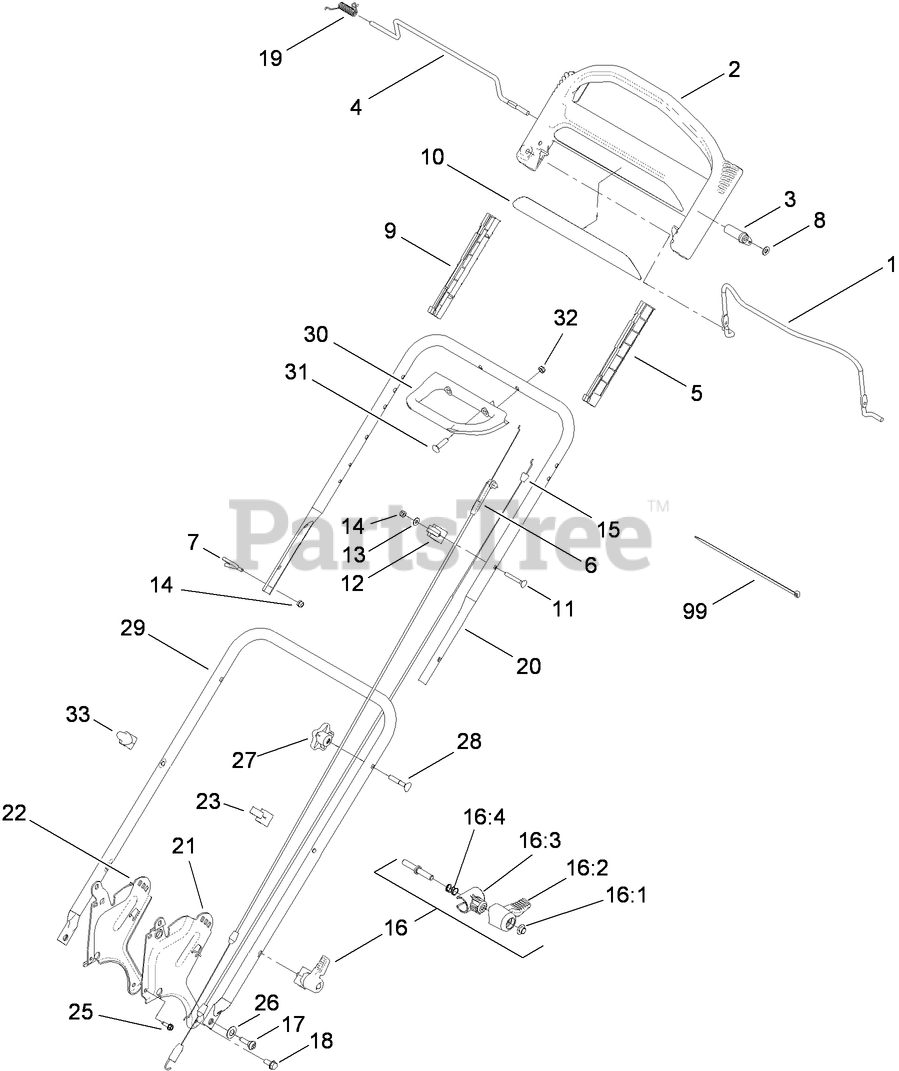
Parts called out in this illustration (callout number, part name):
2	HANDLE-CONTROL
3	LEVER-TRACTION
5	GUIDE-LH
6	CABLE-BRAKE
7	GUIDE-ROPE
8	WASHER-PLAIN
9	GUIDE-RH
10	DECAL-HANDLE
11	SCREW
13	WASHER-FLAT
14	NUT-LOCK, NI
15	CABLE-TRACTION
16	QUICK RELEASE ASM
16:2	LEVER
16:3	ANCHOR-SPRING
16:4	SPRING-COMPRESSION
17	SCREW-SHOULDER, BHTF
18	SCREW-THD ROLL, HWH
20	HANDLE-UPPER
21	BRACKET-HANDLE, LH
22	BRACKET-HANDLE, RH
23	GUIDE-CABLE
25	SCREW-HWHTF
26	WASHER-SPRING, CONICAL
27	KNOB-HANDLE
29	HANDLE-LOWER
31	BOLT-CARRIAGE
32	NUT-LOCK, NI
33	GUIDE-ROPE, FLEXIBLE
99	TIE-CABLE
